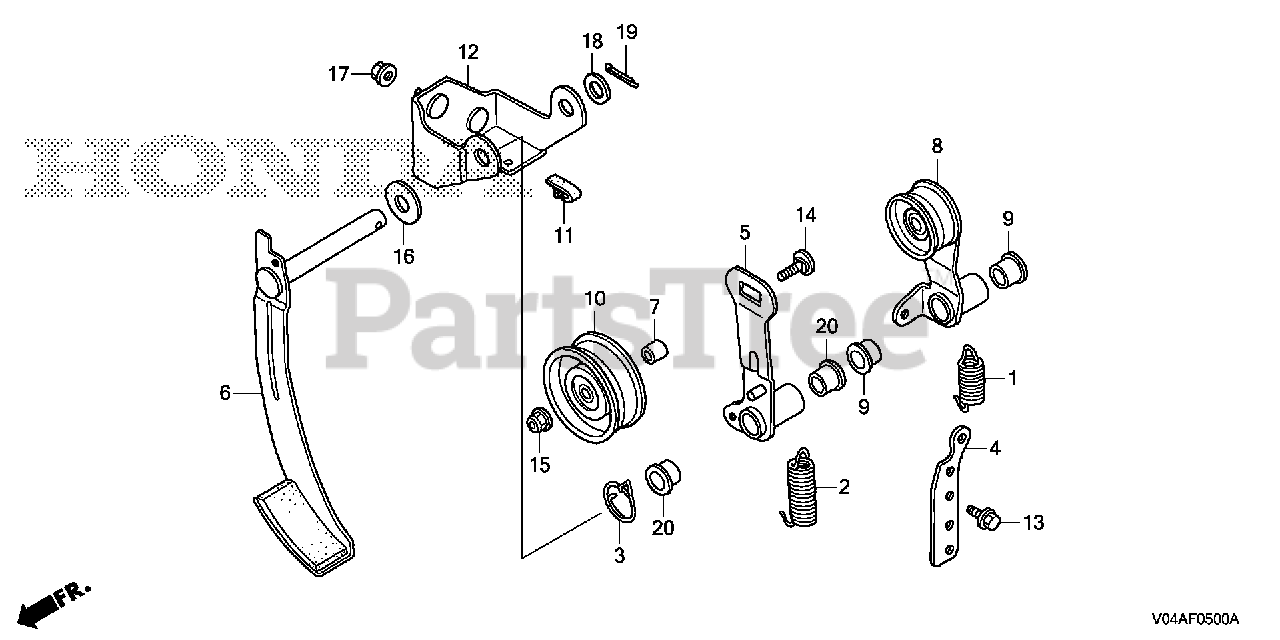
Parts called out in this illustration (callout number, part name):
1	SPRING, WHEEL TENSION RETURN
2	SPRING, AUGER TENSIONER RETURN
3	SPRING, BRAKE ARM
4	STAY, TENSIONER SPRING
5	ARM, AUGER TENSIONER
6	ARM, AUGER BRAKE
7	COLLAR, ROLLER
8	ARM, WHEEL TENSIONER
9	BUSH, TENSIONER ARM
11	RUBBER, STOPPER
12	BRACKET, TENSION ARM
13	BOLT, FLANGE (6X12) (CT200)
14	BOLT, ROLLER
15	NUT, SELF-LOCK (8MM) (CLINCH)
16	WASHER, BRAKE ARM
17	NUT, FLANGE (8MM)
18	WASHER, PLAIN (12MM)
19	PIN, SPLIT (3.0X18)
20	BUSH, TENSIONER ARM
20	BUSH, CHANGE ARM
